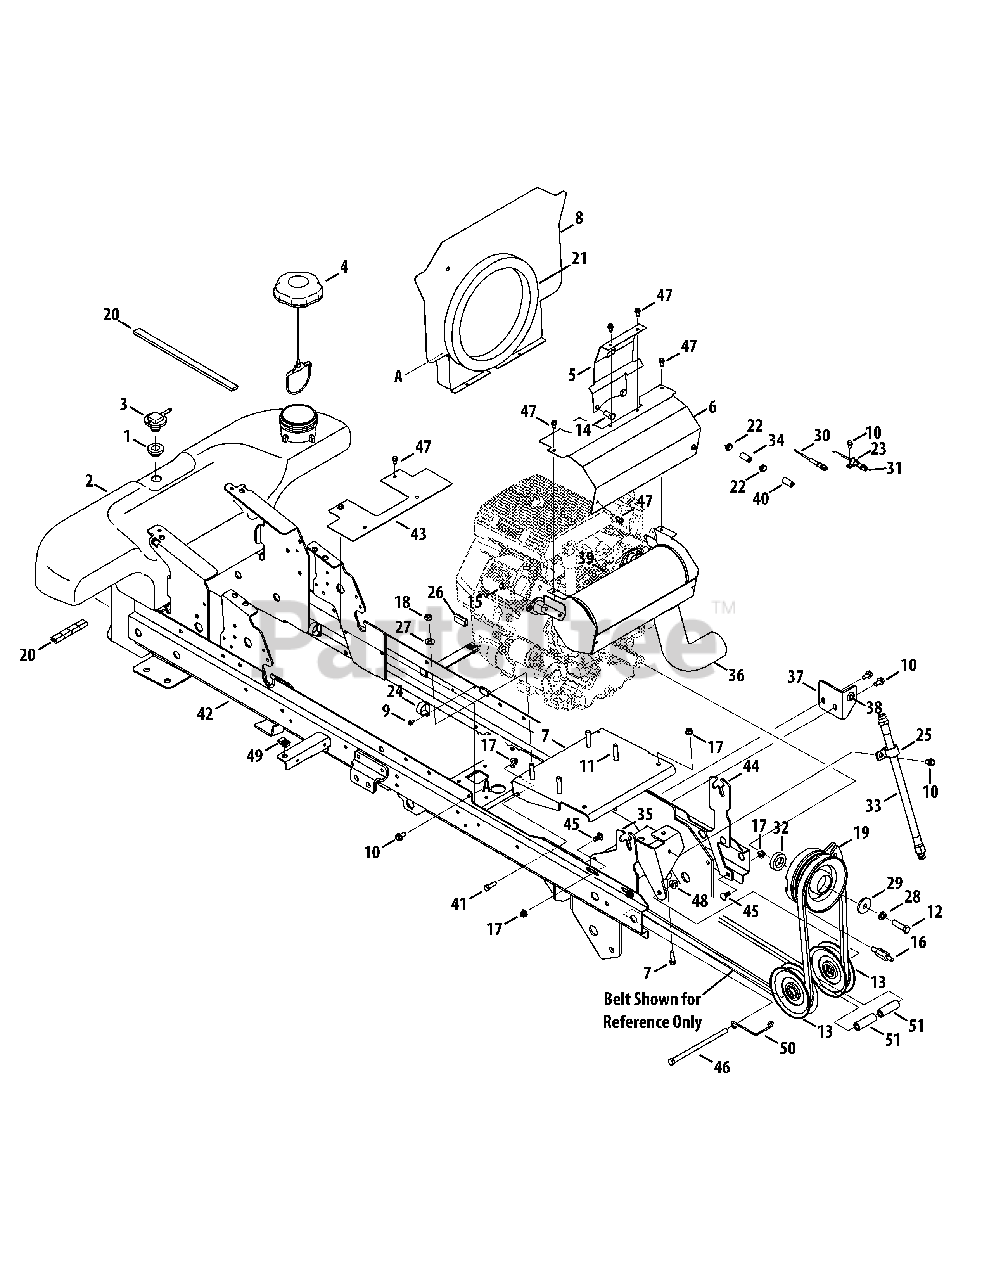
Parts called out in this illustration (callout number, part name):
1	Rubber Grommet, 23.0 x 3.55
2	Fuel Tank
3	Fuel Rollover Valve
4	Fuel Cap, 3.50
5	Clutch Heat Shield
6	Engine Upper Shield
7	Engine Mount Bracket
8	Engine Baffle Plate
9	AB Screw, #10-16 x .500
10	Screw, 5/16-18 x .750
11	Hex Screw, 3/8-24 x 1.75
12	Hex Screw, 7/16-20 x 1.50
13	Idler Pulley
14	Hex Screw, 3/8-16 x .750
15	Hex Screw, M6-1.0 x 10
16	Clutch Stop Stud
17	Flange Lock Nut, 5/16-18
18	Hex Lock Nut, 3/8-24
20	Tape Foam, .75 x .25
21	Intake Gasket Foam
22	Hose Clamp
23	Clamp, 9/16
24	Hose Clamp, 1.0
25	Clamp, 1.0
27	Spring Washer, .401 x .870 x .060
28	Lock Washer, 7/16
29	Flat Washer, .45 x 1.5 x .172
30	Choke Control Cable
31	Throttle Control Cable
32	PTO Spcr., 1.13 x 1.62 x .21
33	Oil Drain Hose
34	Low Permeation Fuel Hose
35	Hood Tilt Bracket
36	Pipe Assembly Heat Shield
37	Exhaust Bracket
38	Grommet, .875 OD x .375 ID x .188
39	Twin Muffler
41	Hex Screw, 5/16-18 x 1.00
42	Frame (GS Models)
44	Hood Pivot Bracket
45	Carriage Bolt, 5/16-18 x .750
46	Hex Screw, 3/8-16 x 7.25
47	Screw, 1/4-20 x .625
48	Flange Lock Nut, 3/8-16
49	U-Nut, 5/16-18
50	Belt Guide
51	Idler Spacer, .41 x .875 x 2.19
